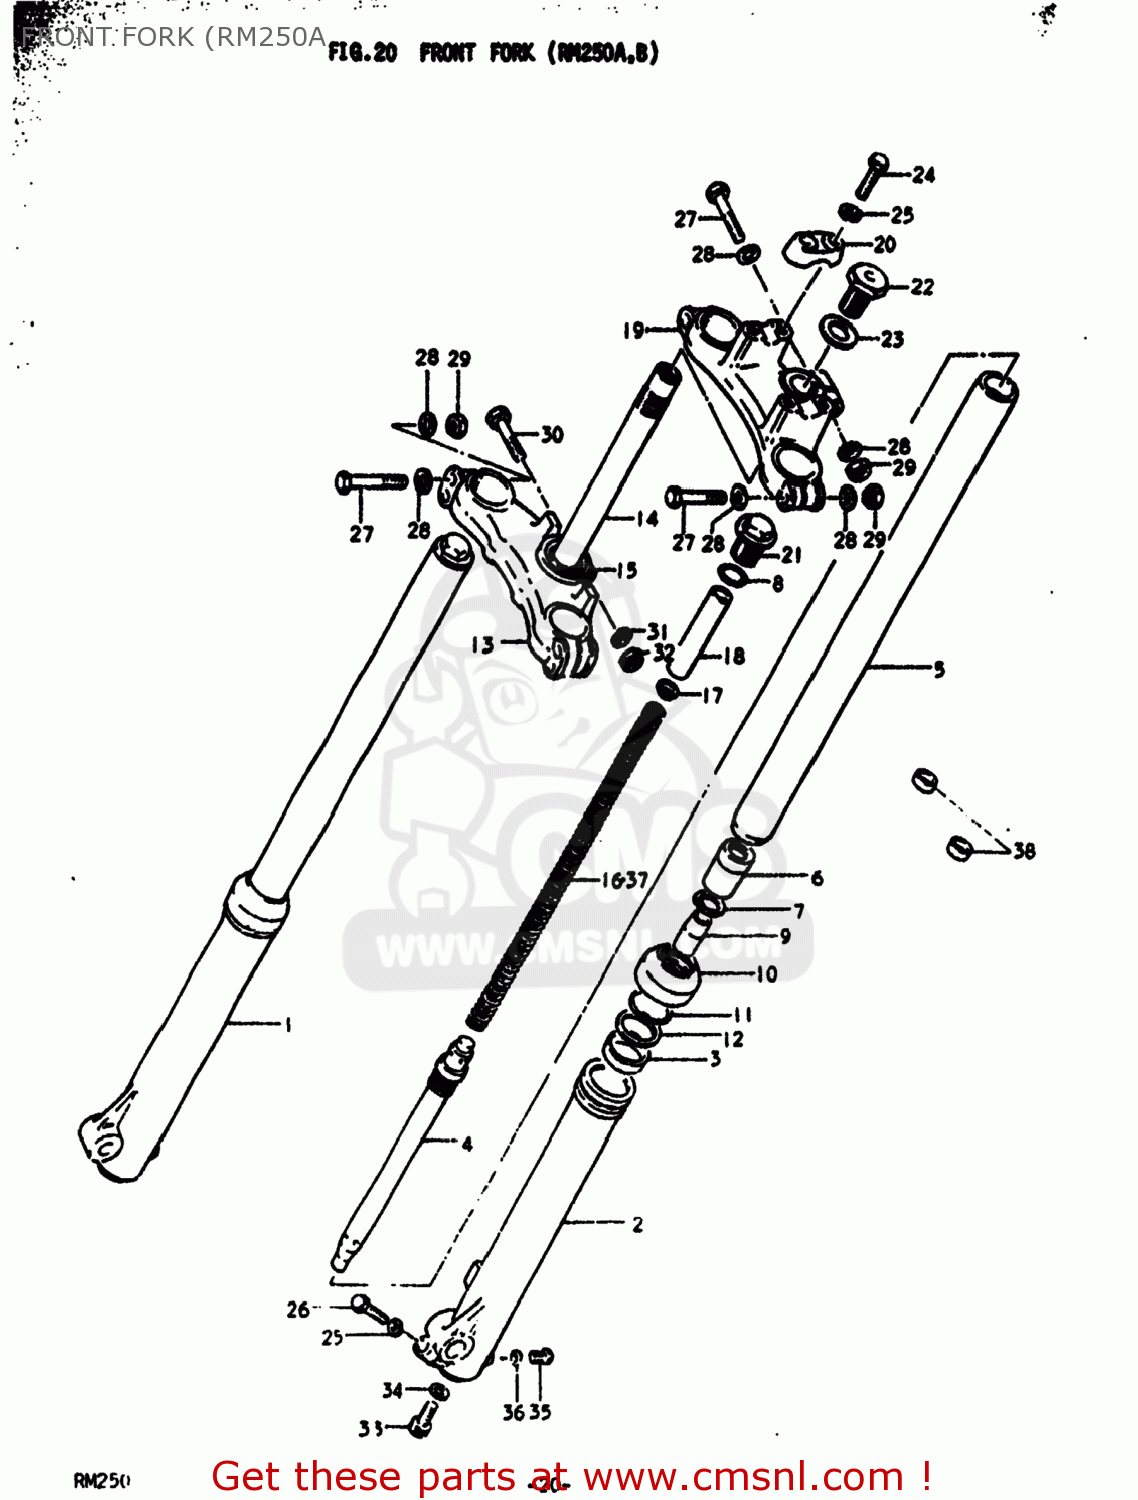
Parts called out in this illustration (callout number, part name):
0	DAMPER SET
1	TUBE,OUTER,RIGHT
2	TUBE,OUTER,LEFT
3	OIL SEAL,FRONT FORK
4	CYLINDER,FRONT FORK
5	TUBE,FORK,INNER
6	PISTON,FORK INNER TUBE
7	RING
8	O RING
9	PIECE,OIL LOCK
10	SEAL,DUST
11	CIRCLIP,FORK OIL SEAL
12	RING,FORK BACK UP
13	STEM,STEERING
14	STEM,STEERING
15	RACE,STEERING OUTER LWR
16	SPRING
17	GUIDE,FRONT FORK SPRING C
18	SPACER,SPRING
19	HEAD,STEERING STEM
20	HOLDER,HANDLEBAR
21	BOLT,FORK
22	CAP
23	WASHER
24	Bolt
25	LOCK WASHER
26	BOLT (8X30)
27	BOLT 8X55
28	WASHER
29	NUT
30	BOLT 10X60
31	LOCK WASHER
32	NUT
33	BOLT,FORK CYLINDER(10X25)
34	GASKET (NAS)
35	SCREW
36	GASKET,DRAIN,PLUG (NAS)
37	SPRING
